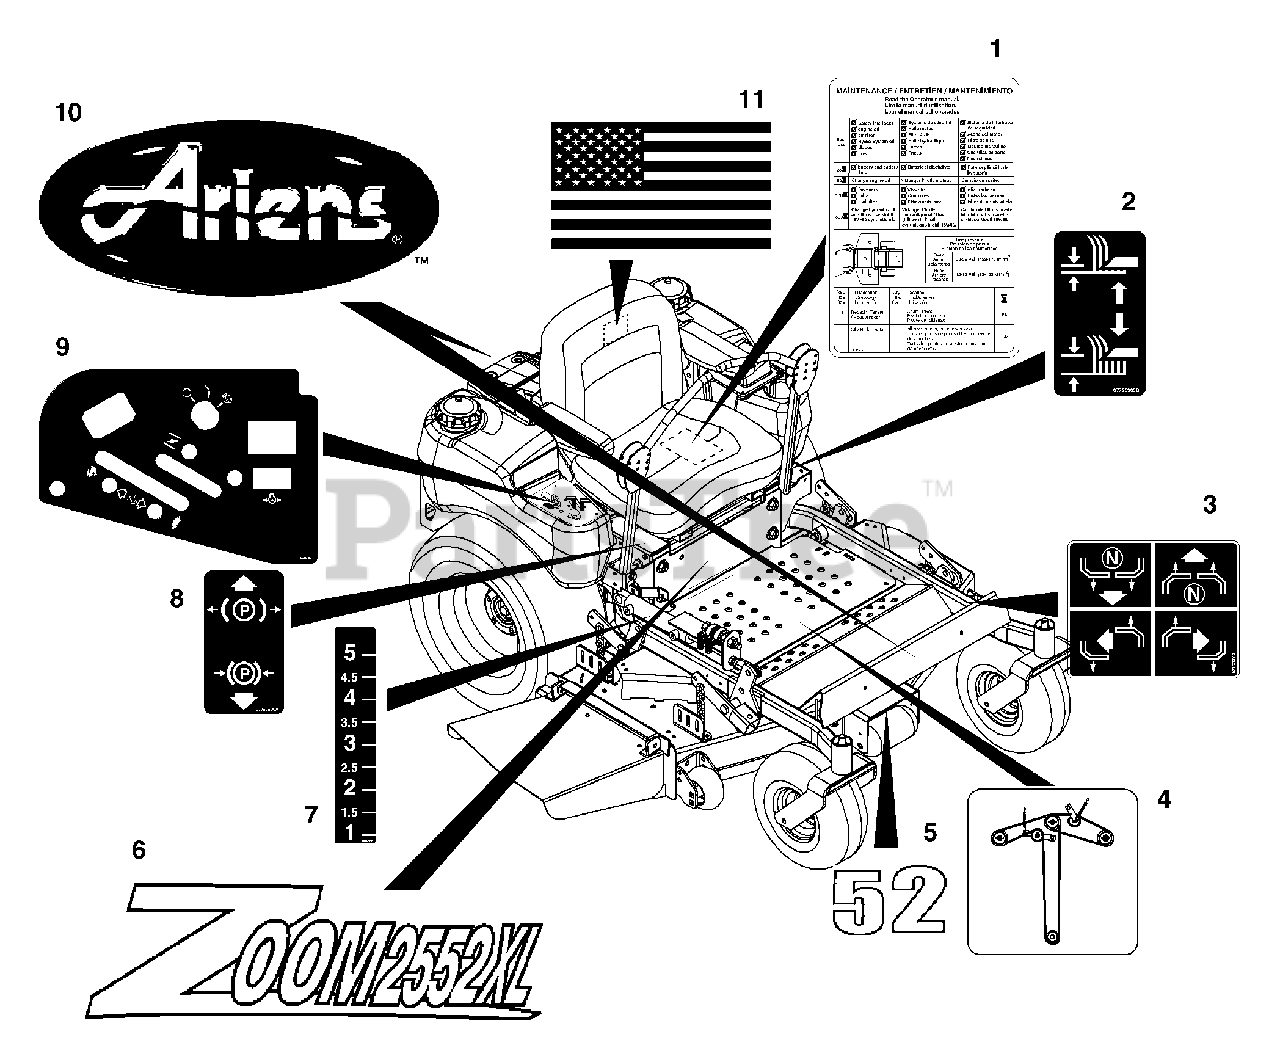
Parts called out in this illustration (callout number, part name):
1	DECAL, MAINTENANCE INSTRUCTION
2	DECAL- LIFT LEVER
3	DECAL, INSTRUCTIONAL-STEERING
4	DECAL, GRAVELY BELT DIAGRAM
5	DECAL - 52"
6	DECAL, ZOOM 2552 XL
7	DECAL, HEIGHT OF CUT
8	DECAL, PARKING BRAKE LEVER
9	DECAL CONTROL PANEL
10	DECAL, ARIENS JEWEL
11	DECAL, AMERICAN FLAG
